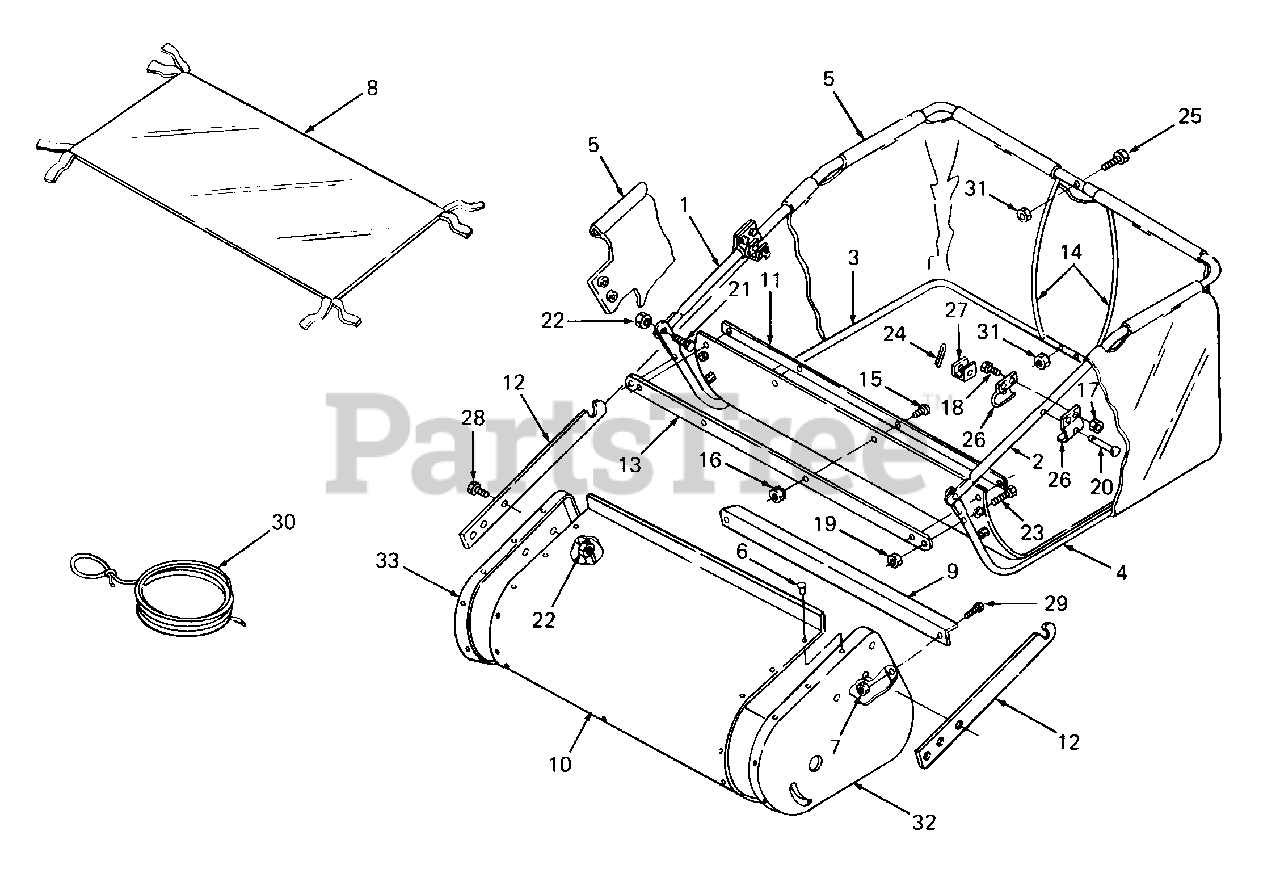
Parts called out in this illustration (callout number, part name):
1	Tube, Upper Hopper RH
2	Tube, Upper Hopper LH
3	Tube, Lower Hopper RH
4	Tube, Lower Hopper LH
5	Bag, Hopper
7	Nut, Hex Lock, 1/4-20 Thd
8	Screen, Wind, 32"
9	Brace, Rear Support
11	Retainer, Skirt
12	Arm, Bag Mount
13	Strap, Bag Frame
14	Rod, Hopper Support
15	Screw, Truss Hd, Slotted #10-32 X 5/8 Lg
16	Nut, Hex Lock, #10-32 Thd
17	Nut, Hex Lock, 5/16-18 Thd
18	Bolt, Hex, 5/16-18 X 3/4 Lg
19	Nut, Hex Lock, 1/4-20 Thd
20	Pin, Clevis, 3/8 Dia X 3
21	Bolt, Hex, 3/8-16 X 3/4 Lg
22	Nut, Hex Lock, 3/8-16 Thd
23	Bolt, Hex, 1/4-20 X 1.25 Lg
24	Pin, Cotter, 1/8 Dia X 3/4 Lg
25	Bolt, Curved Head, 1/4-20 X
26	Clamp, Hopper Mount
27	Clevis, Bag Retainer
28	Bolt, Hex, 3/8-16 X.75 Lg GR5
29	Bolt, Hex, 1/4-20 X 1/2 GR5
30	Rope, Hopper
31	Nut, Hex Lock, 1/4-20 Thd
32	Plate, End LH
33	Plate, End RH
